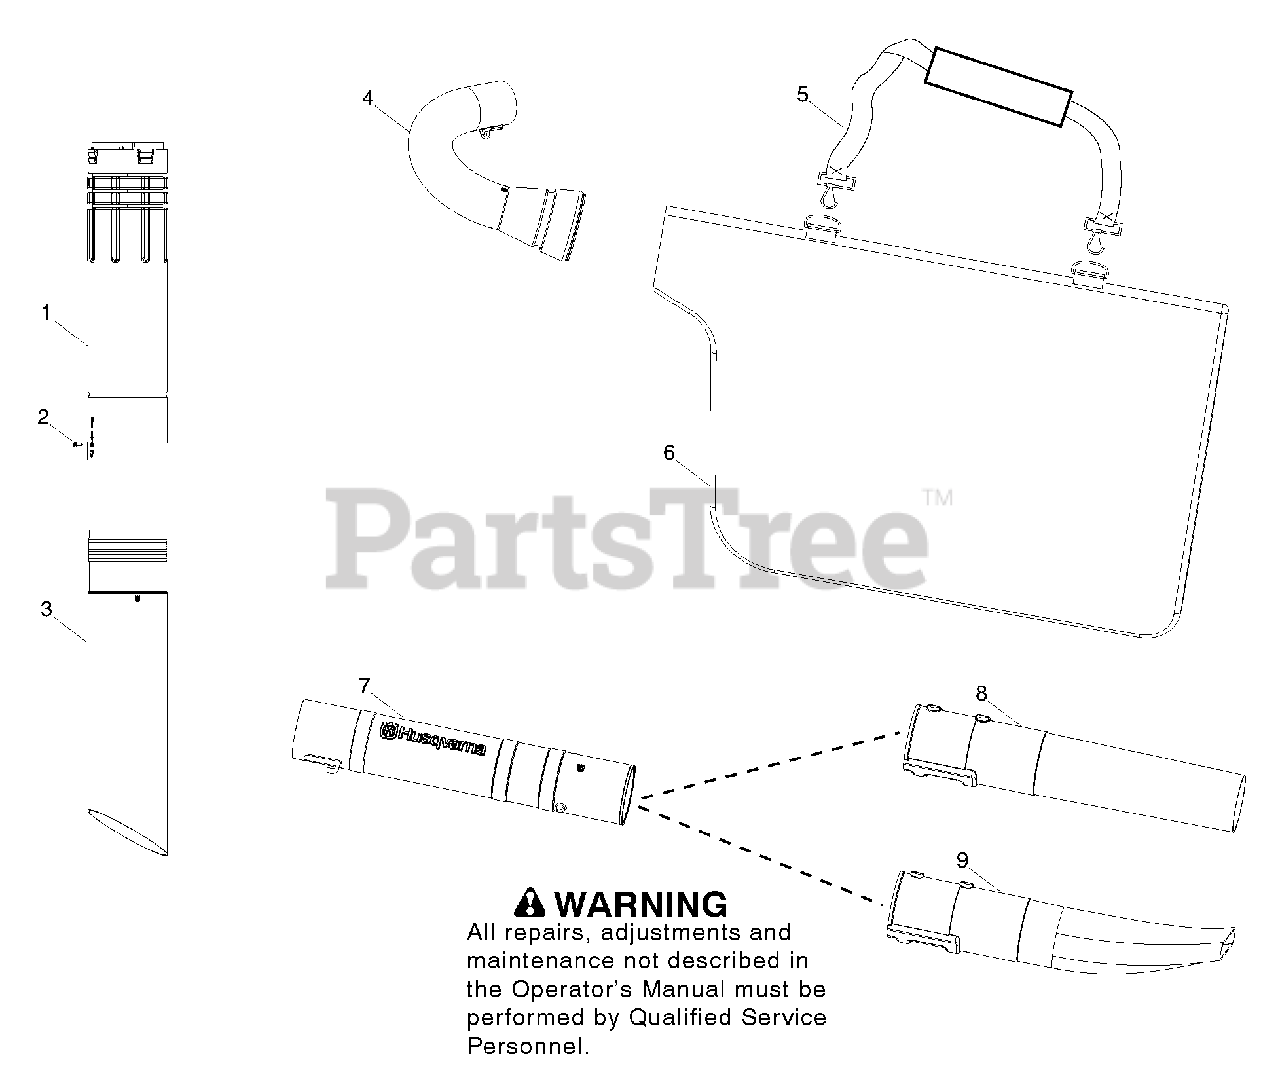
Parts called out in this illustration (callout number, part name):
1	Assy - Upper vac tube with adapter
3	Tube - Lower vac
4	Elbow - Vac
5	Strap - Carrying
6	Assy - Vac bag
7	Assy - Tube - upper blower w/barrier
8	Tube - Lower blower (round)
9	Tube - Lower blower (flare)
